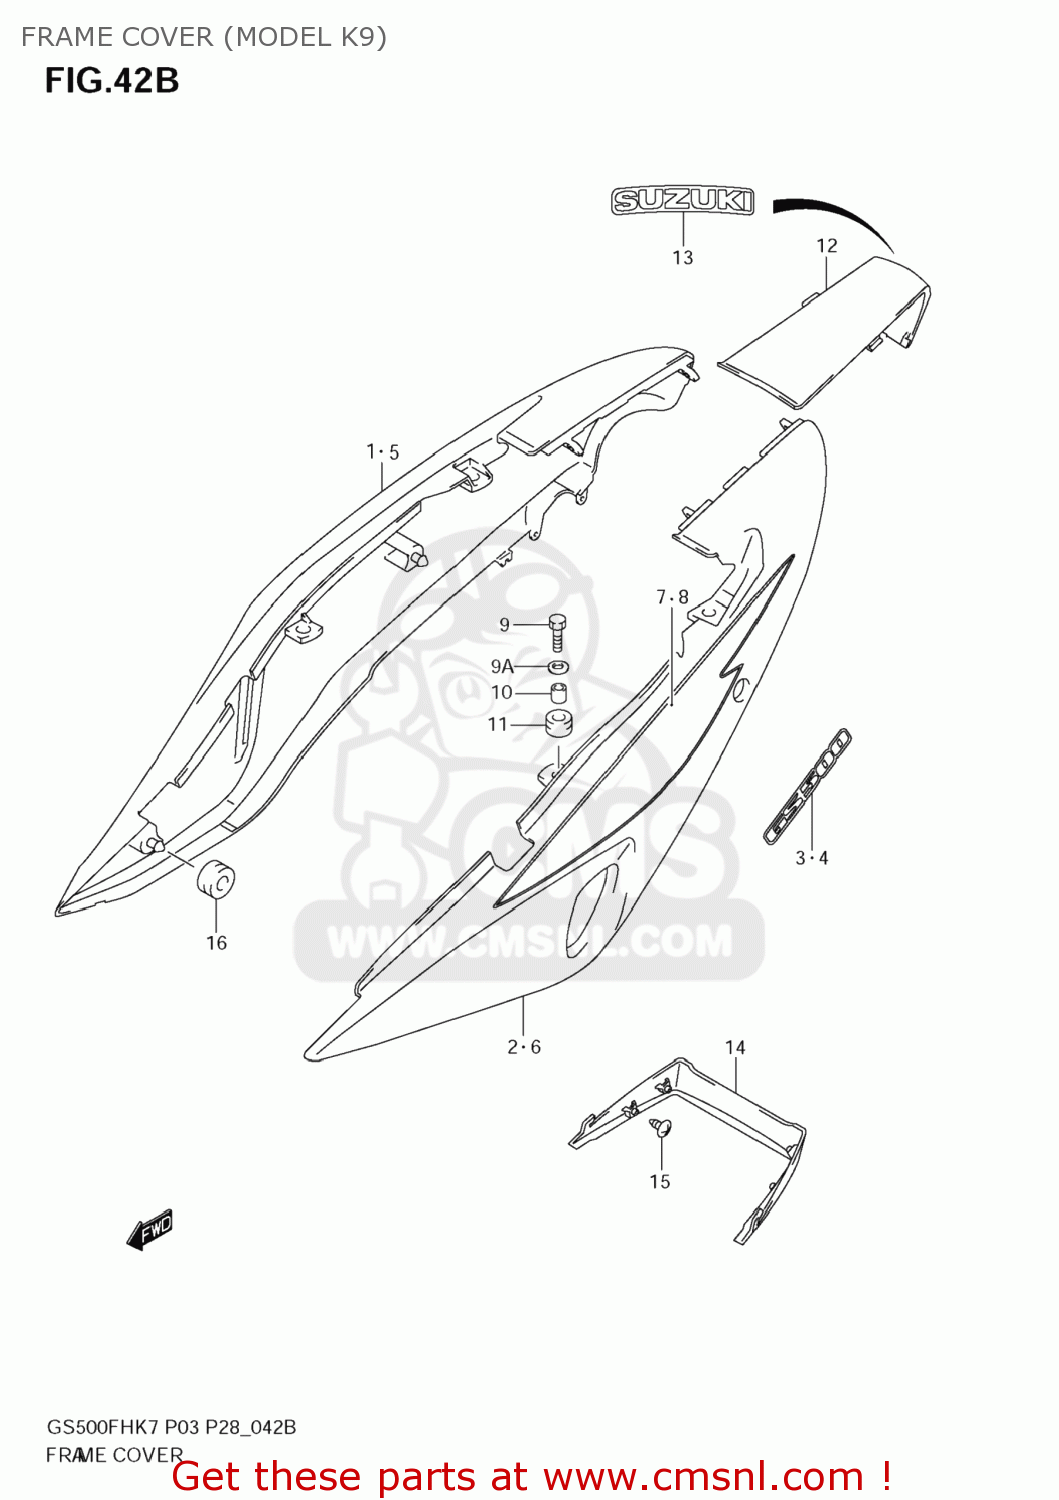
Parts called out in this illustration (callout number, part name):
1	COVER, FRAME RH (BLACK)
2	COVER, FRAME LH (BLACK)
3	TAPE, FRAME COVER, R NOT FOR US MARKET
4	TAPE, FRAME COVER, L NOT FOR US MARKET
5	COVER FRAME WHITE
6	COVER, FRAME G
7	TAPE,FRAME COVE
8	TAPE,FRAME COVE
9	BOLT
9A	WASHER
10	SPACER(6.5X9X9)
11	CUSHION
12	COVER,FRAME CEN
13	EMBLEM"SUZUKI"S
14	COVER, LOWER
15	SCREW
16	CUSHION
